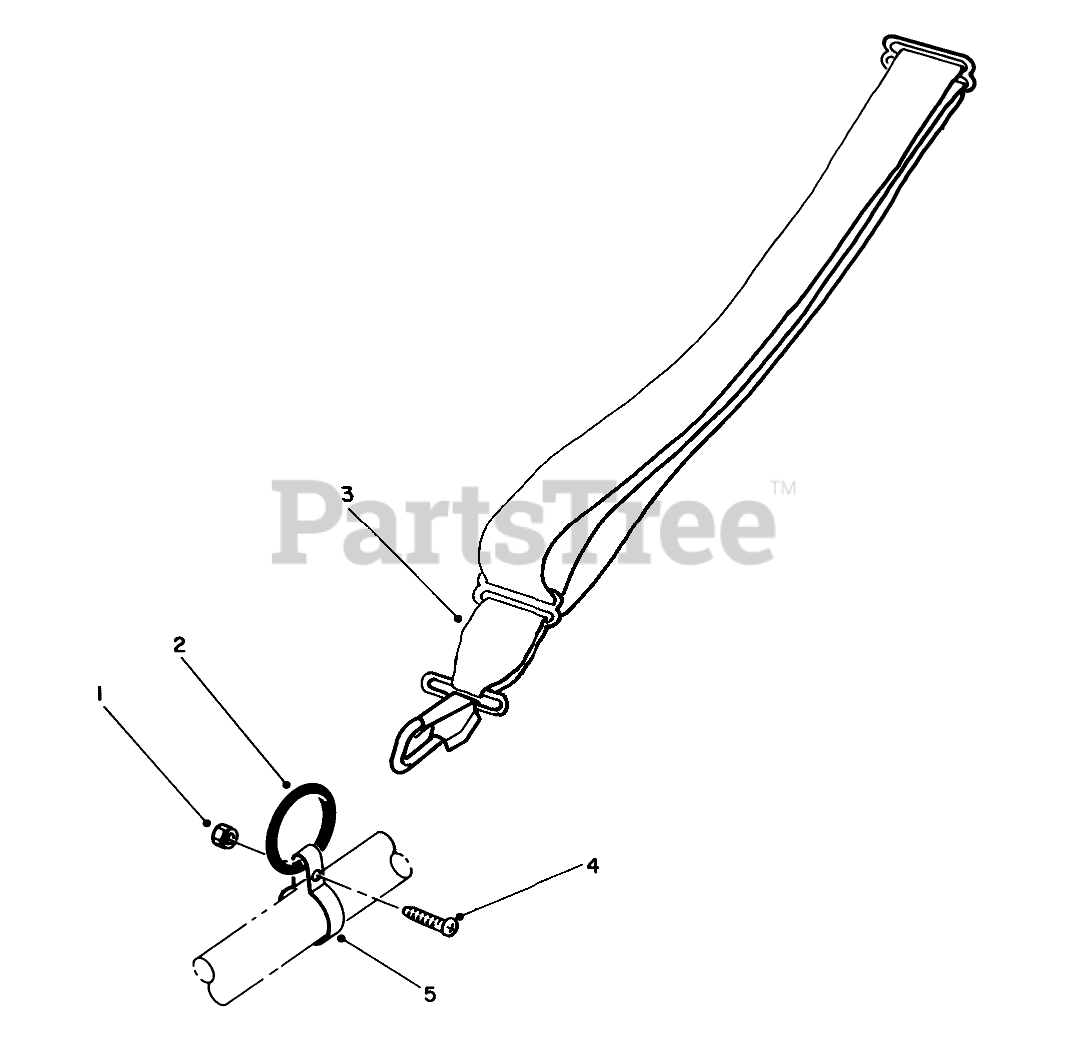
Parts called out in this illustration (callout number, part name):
1	Harness
2	Ring
3	Clamp
5	Nut
